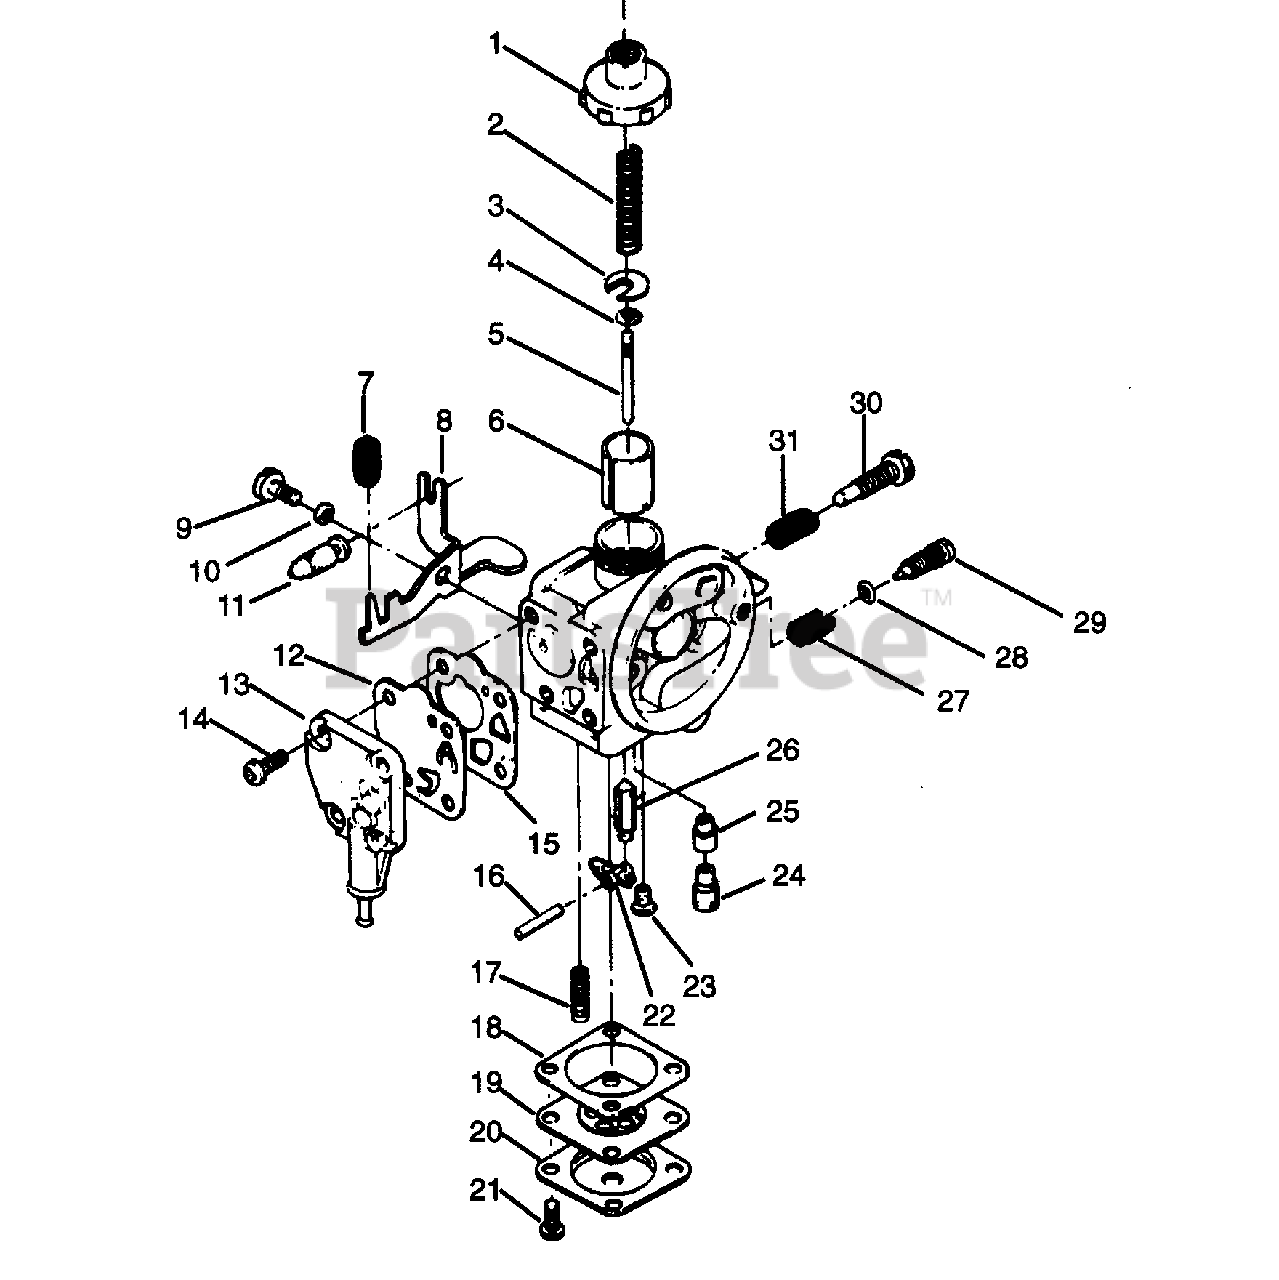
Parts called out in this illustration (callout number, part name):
1	Body Cap
2	Throttle Spring
3	Retainer
12	Diaphragm
13	Pump Cover
19	Diaphragm Ass'y.
